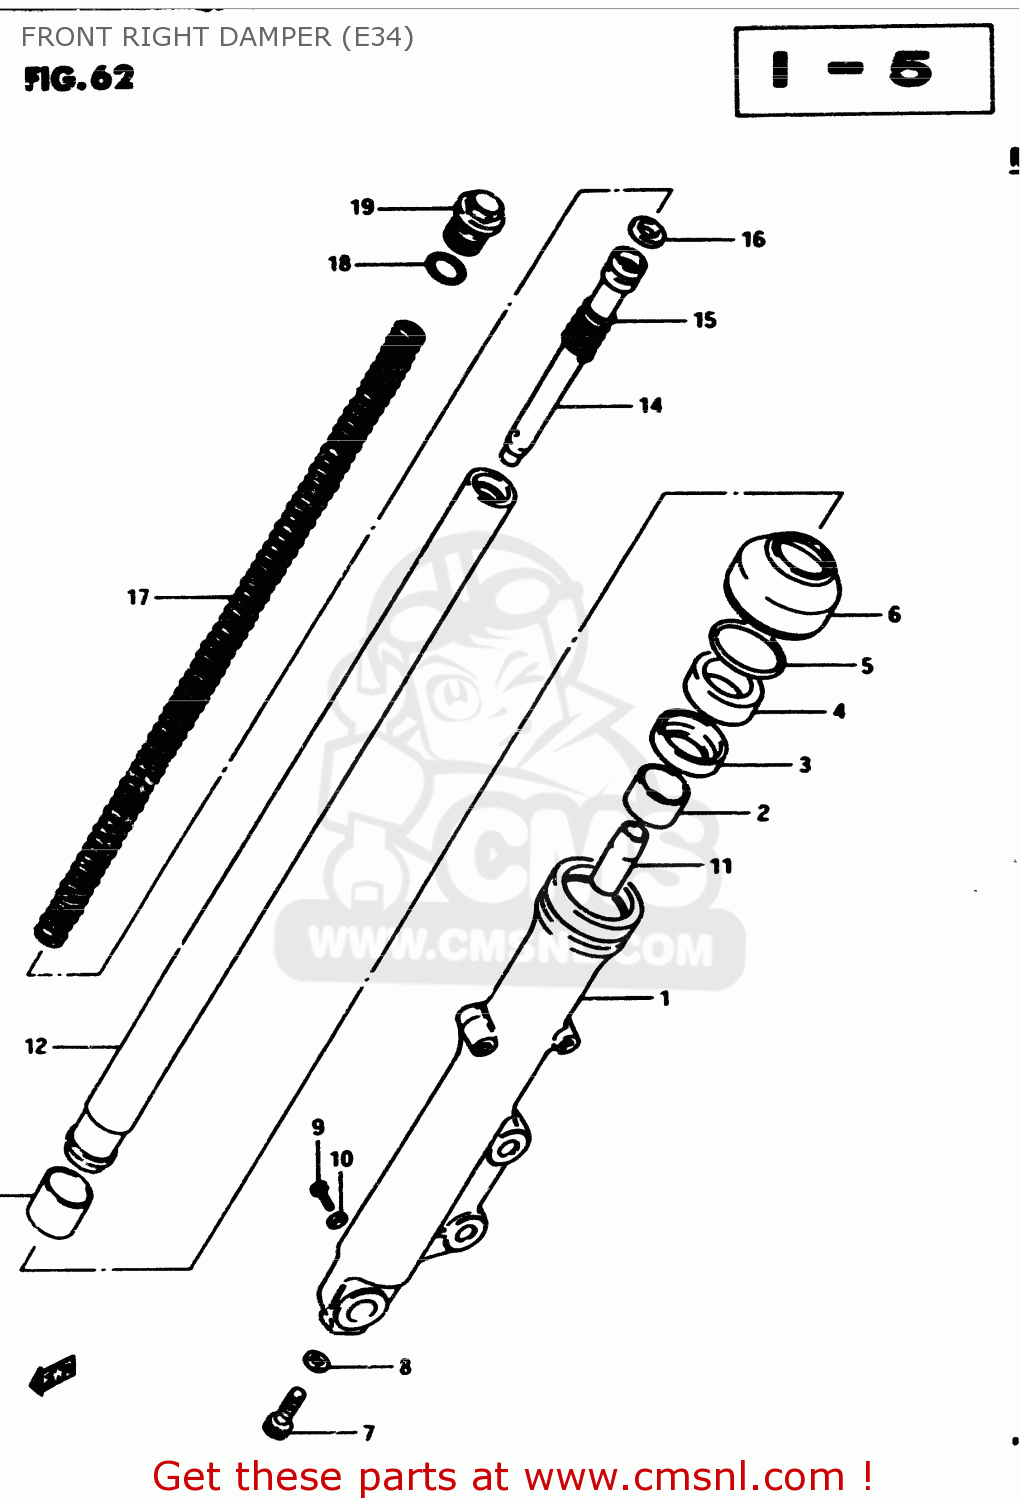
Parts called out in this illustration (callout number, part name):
1	OUTER TUBE RH
2	BUSH,GUIDE
3	SPACER,OIL SEAL
4	OIL SEAL,FRONT FORK
5	CIRCLIP,FORK OIL SEAL
6	DUST SEAL
7	BOLT(8X27)
8	GASKET (NAS)
9	BOLT
10	GASKET,DRAIN,PLUG (NAS)
11	PIECE,OIL LOCK
12	TUBE,INNER
13	BUSH
14	CYLINDER,FRONT FORK
15	SPRING,REBOUND
16	RING,PISTON
17	SPRING,FR.FORK
18	O RING
19	BOLT
